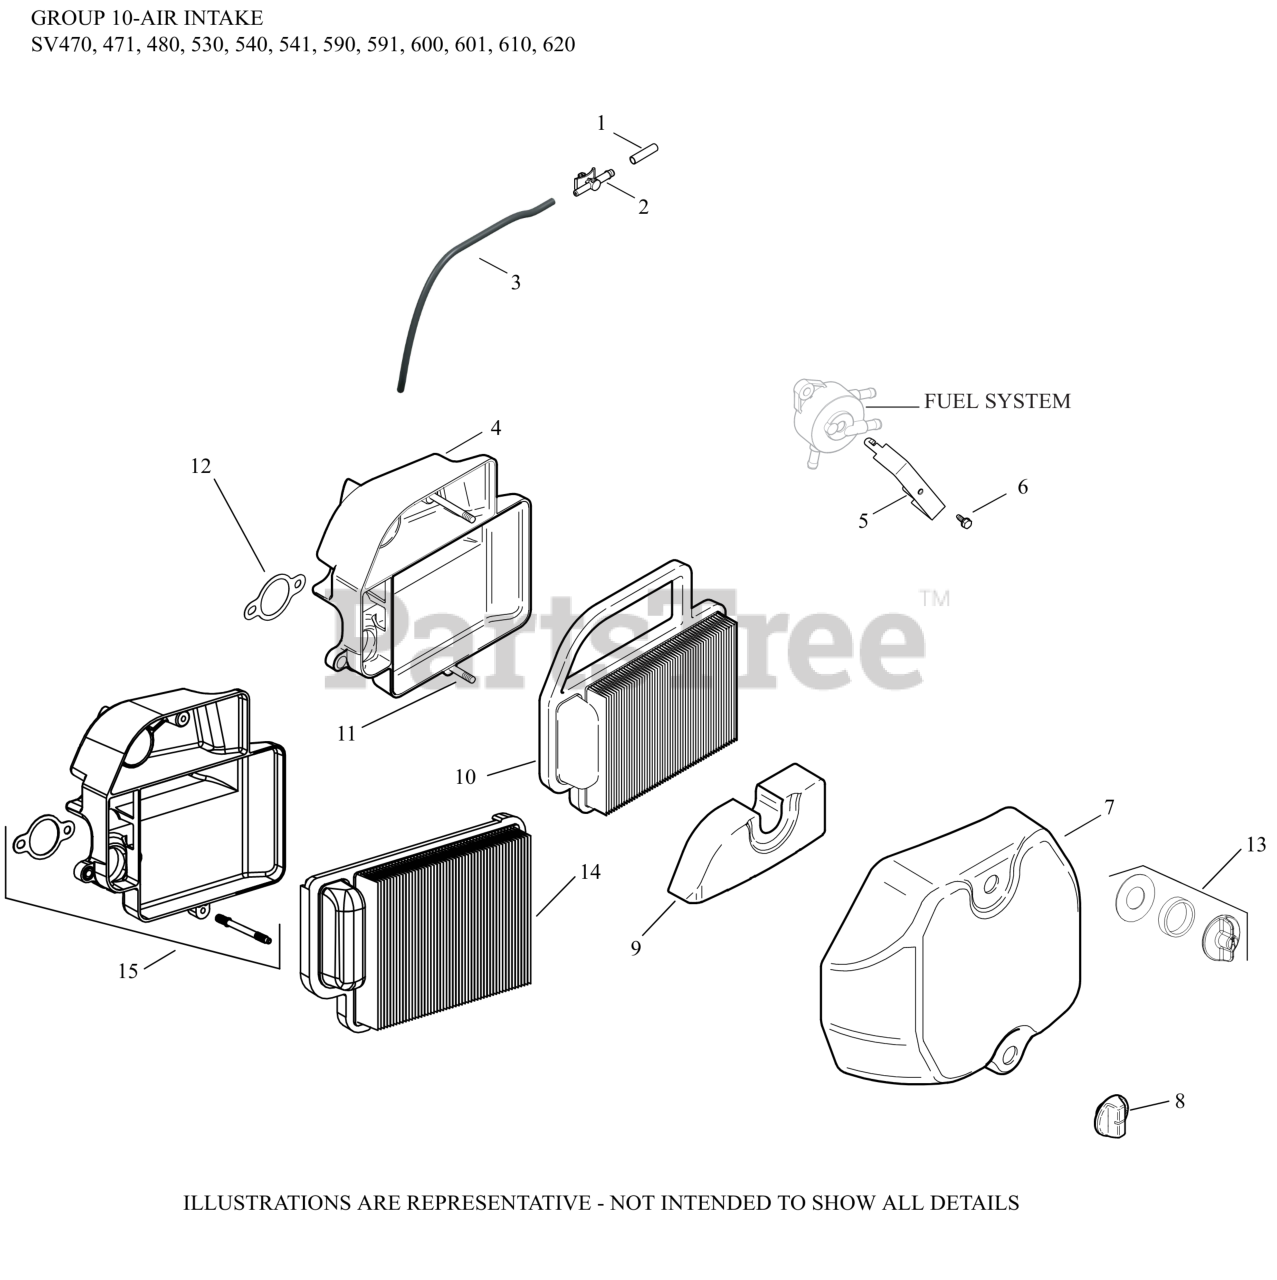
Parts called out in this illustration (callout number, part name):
1	CAP, MASKING
2	CONNECTOR, EVAPORATIVE
3	HOSE, EVAPORATIVE
4	KIT, AIR CLEANER BASE
5	BRACKET, FUEL PUMP
6	SCREW, THRD FRM M4X0.7X10
7	KIT, AIR CLEANER COVER
8	KNOB, COVER
10	AIR CLEANER ELEMENT
11	STUD, AIR CLEANER BASE
12	GASKET, AIR CLEANER BASE
13	KIT, KNOB W/SEAL
